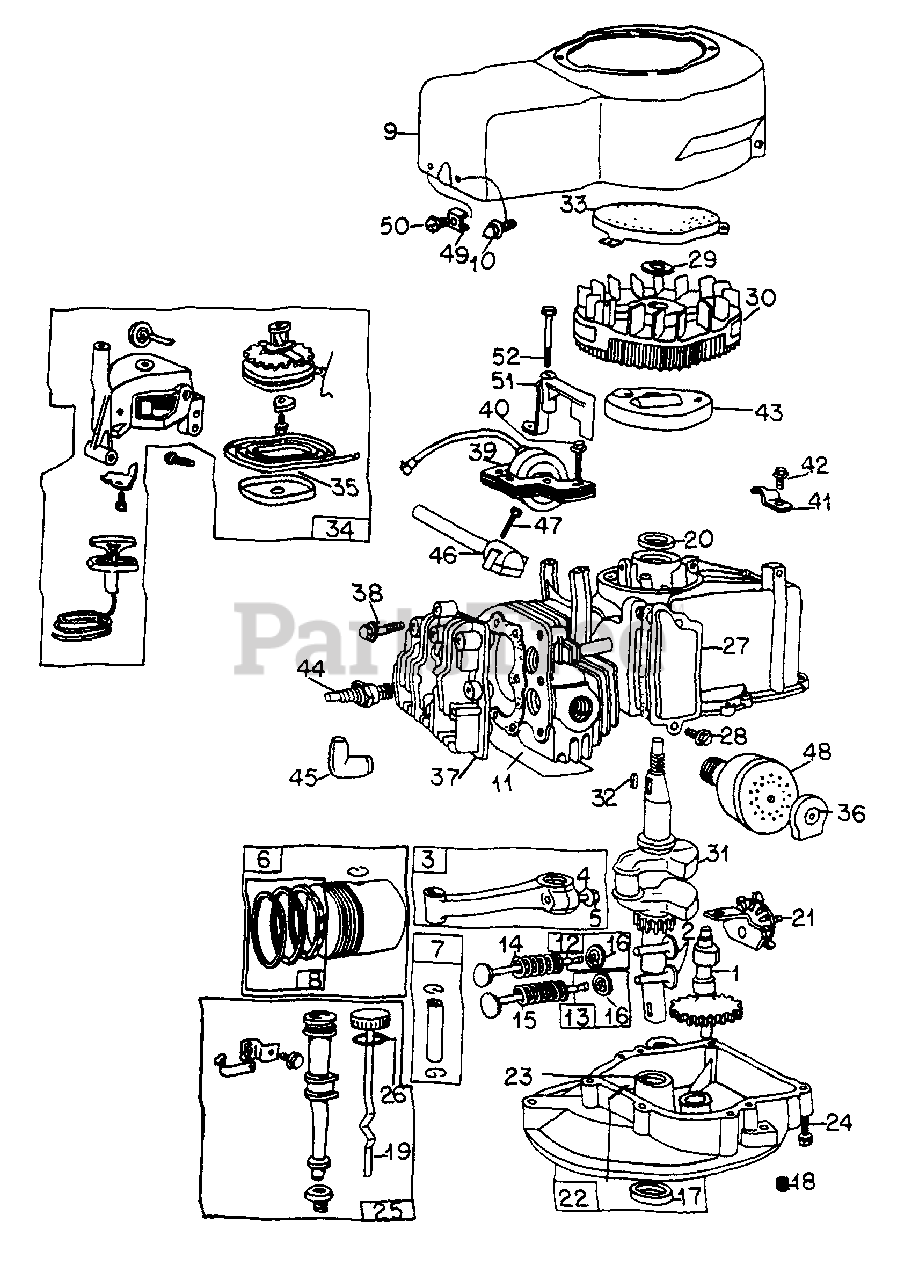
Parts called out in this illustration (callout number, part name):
2	TAPPET, VALVE
3	ROD ASSY, CONNECTING STD
4	LOCK, SCREW HEAD
5	SCREW, CONNECTING ROD
6	PISTON ASSY, STANDARD
7	PIN, PISTON & RETAINER - STANDARD
8	RING SET, PISTON CHROME - STANDARD
8	RING SET, PISTON - STANDARD
9	HOUSING, BLOWER
10	SCREW, BLOWER, HOUSING
11	SHIELD, CYLINDER
12	VALVE, INTAKE
13	VALVE, EXHAUST
14	SPRING, INTAKE VALVE
15	SPRING, EXHAUST VALVE
16	RETAINER, VALVE SPRING
18	PLUG, OIL DRAIN
20	SEAL, OIL
21	SLINGER, OIL GEAR BRACKET
23	BUSHING, OIL SUMP
24	SCREW, SUMP MOUNTING
25	FILLER, OIL
26	RING, OIL FILLER CAP
27	BREATHER, VALVE CHAMBER
28	SCREW, BREATHER MOUNTING
29	WASHER, FLYWHEEL
32	KEY, FLYWHEEL
33	SCREEN, ROTATING
34	STARTER, VERTICAL PULL
35	SPRING, VERTICAL PULL STARTER
36	DEFLECTOR MUFFLER
37	HEAD, CYLINDER
38	SCREW, CYLINDER HEAD
39	ARMATURE, MAGNETO
40	SCREW, ARMATURE MOUNTING
41	CLAMP, CONDENSER
42	SCREW, CONDENSER
43	COVER, BREAKER POINT
44	PLUG, SPARK (CHAMPION)
45	ELBOW, SPARK PLUG INSULATOR
46	TUBE, FUEL, INTAKE
47	SCREW, INTAKE ELBOW MOUNTING
48	MUFFLER ASSY
49	CLAMP, CASING
50	SCREW W/LOCKWASHER, HEX-HD
51	BLADE, GOVERNOR
